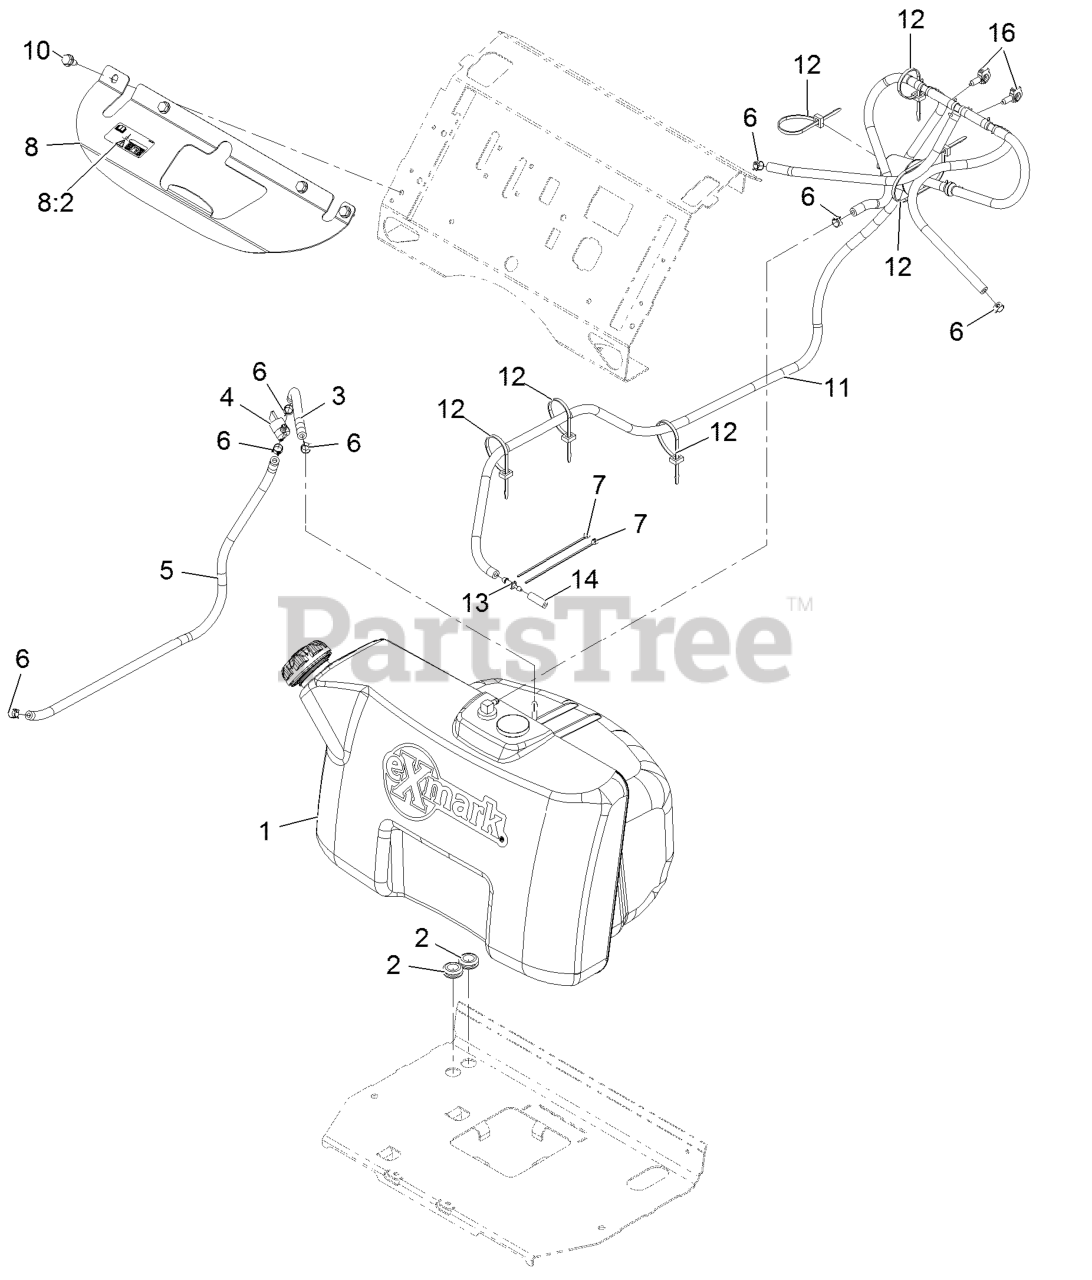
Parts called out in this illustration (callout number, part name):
2	GROMMET
3	HOSE-FUEL
4	VALVE-FUEL
5	HOSE-FUEL
6	CLAMP-HOSE
7	TIE-CABLE
8	BRACKET-TANK
8:2	Decal-Fuel Fill
10	Screw-HWH 5/16-18 X 3/4 Tf
11	VENT ASM
12	TIE-CABLE
13	FITTING-STRAIGHT
14	HOSE-FUEL
16	CLIP-HARNESS
